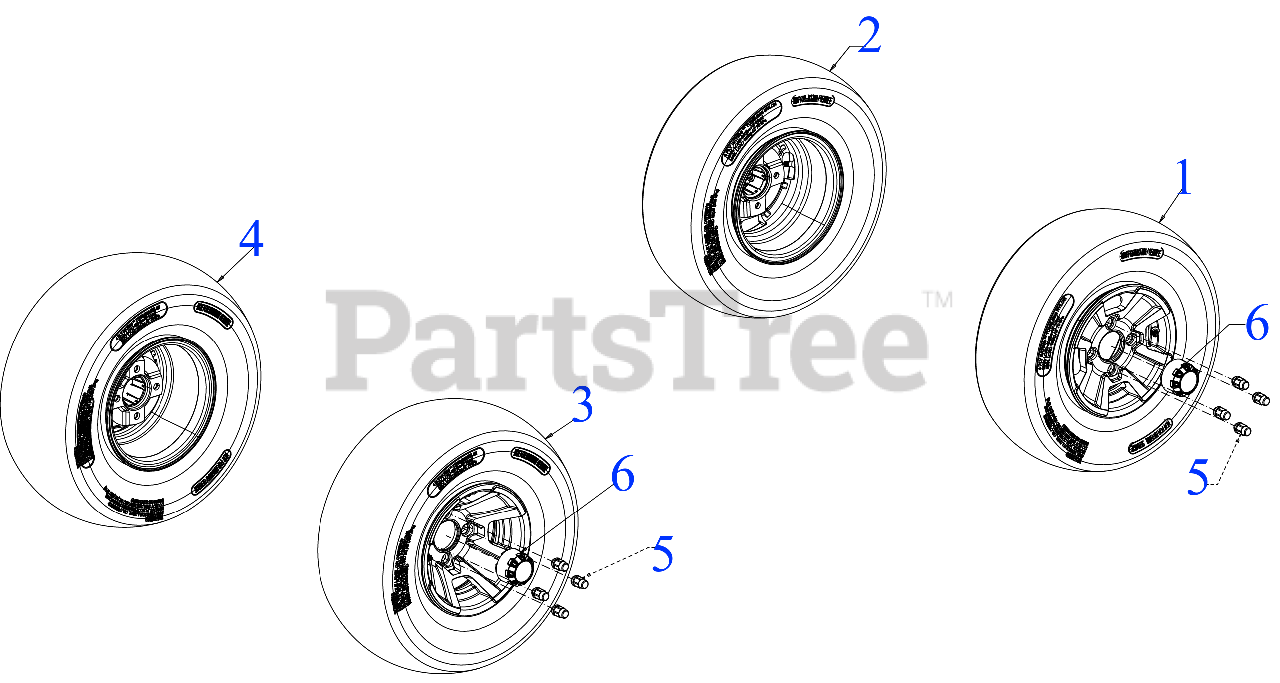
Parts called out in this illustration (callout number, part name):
1	FRONT RIGHT WHEEL ASSEMBLY
2	LEFT FRONT WHEEL ASSEMBLY
3	RIGHT REAR WHEEL ASSEMBLY
4	LEFT REAR WHEEL ASSEMBLY
5	LUG NUT 1/2-20 CHROME
6	WHEEL CENTER CAP
